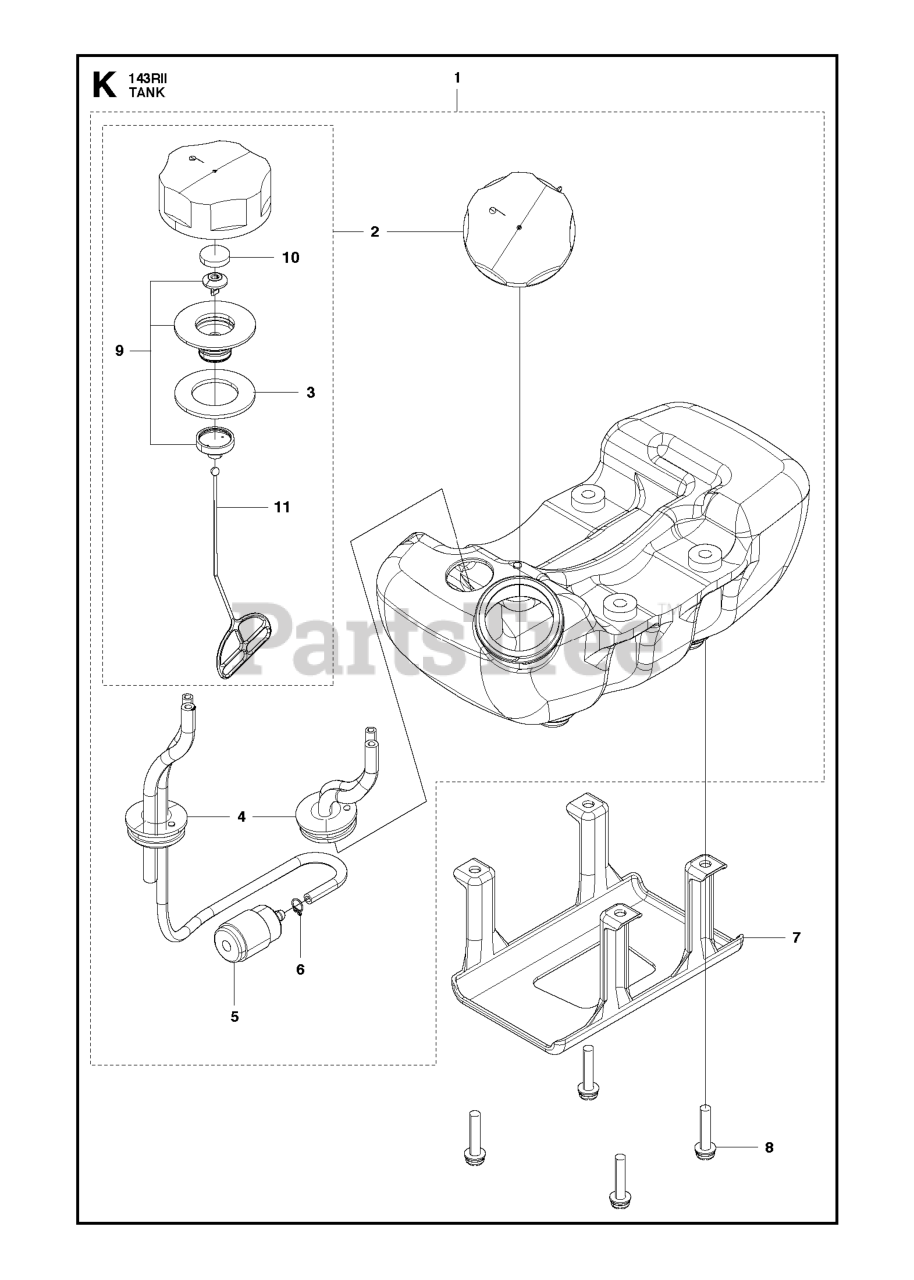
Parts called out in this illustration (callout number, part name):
4	PIPE COMP.
5	RP FUEL FILTER
7	TANK GUARD
